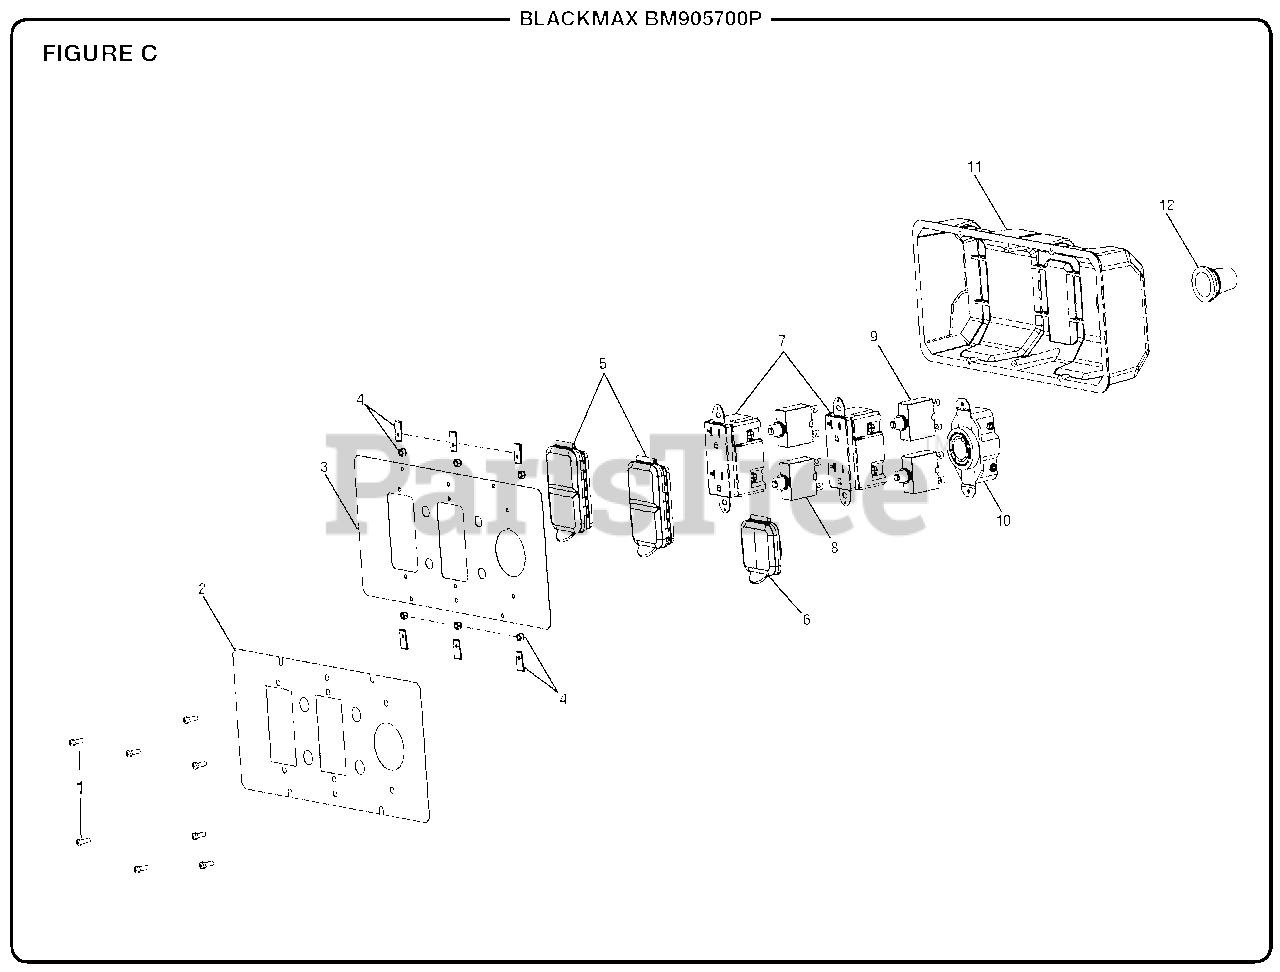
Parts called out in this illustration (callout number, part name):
1	Screw (6-20 x 3/8 in.)
2	Label (Power Outlet)
3	Front Panel
4	U-Clip Nut
5	Outlet Cover (120 Volt)
6	Outlet Cover (240 Volt)
7	Duplex Receptacle (120 Volt)
8	Circuit Breaker, 20 Amp
9	Circuit Breaker, 30 Amp
10	Twist Lock Receptacle (240 Volt)
11	Control Box (Back Panel)
12	Rubber Boot
